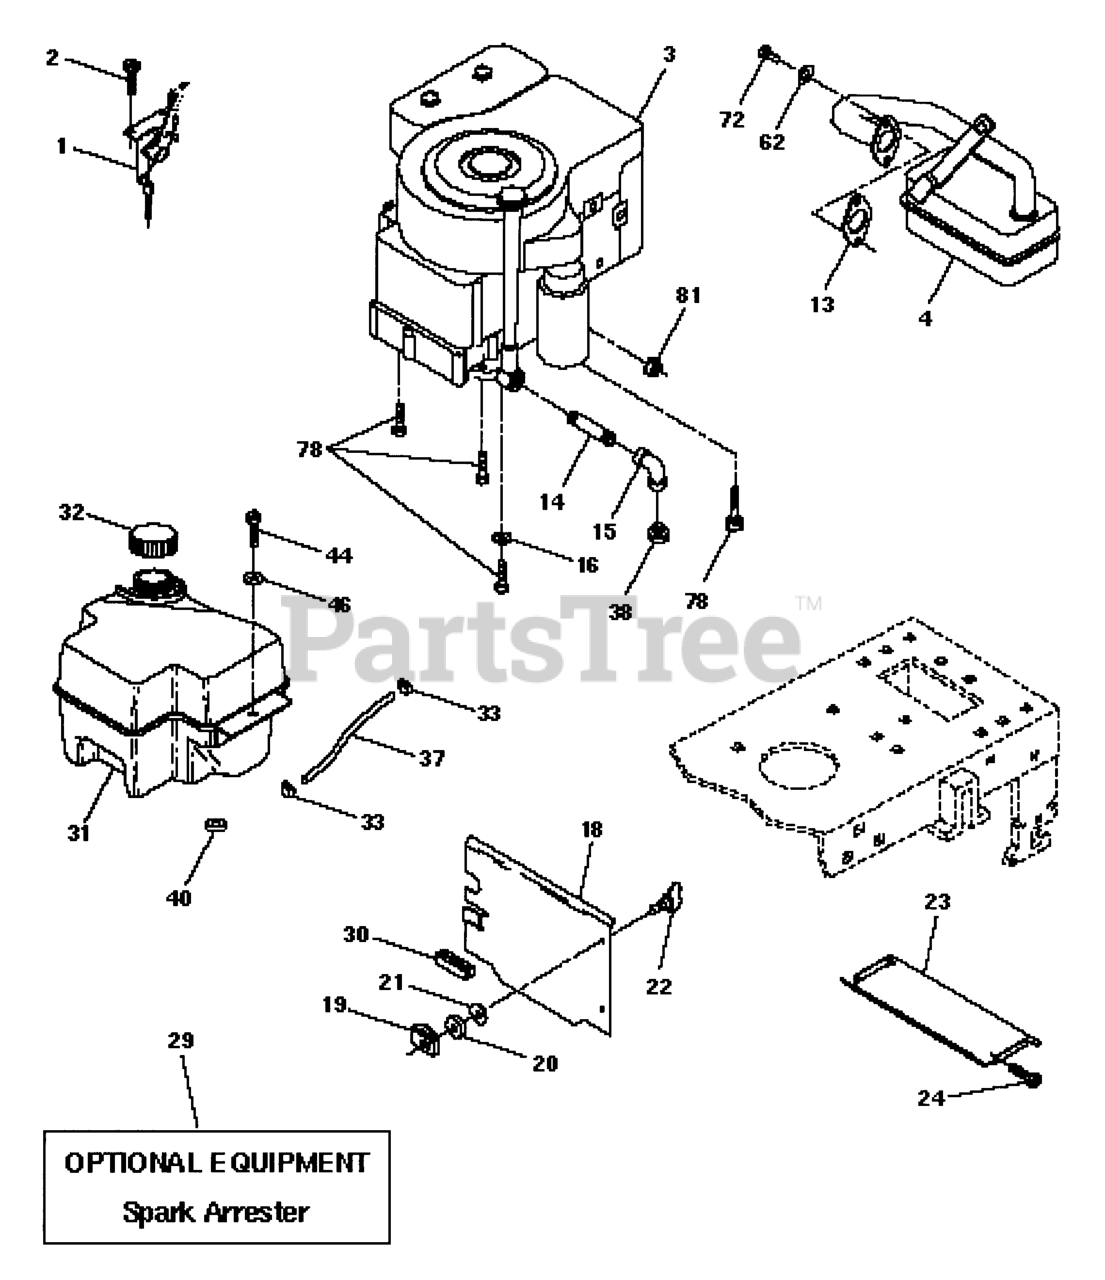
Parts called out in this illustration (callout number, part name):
1	CHOKE CONTROL
2	SCREW LT
4	MUFFLER.SINGLE.B&S.10-12HP
13	GASKET ENGINE
14	Nipple Pipe 3/8 Npt X 3"
15	ELBOW
16	LOCKWASHER
18	HEAT SHIELD
19	RECEPTACLE LT
20	RETAINER LT
21	WASHER
22	STUD 1/4 TURN
23	HEAT SHIELD
29	KIT.SPARK ARRESTOR 794945 B&S
31	FUEL TANK
32	FUEL CAP
33	HOSE CLAMP
37	LINE.FUEL.20
38	Plug Oil Drain
40	BUSHING.SNAP.NYL.BLK.
44	SCREW HEX CRT
46	WASHER
62	WASHER.LOCK.HVY.HLCL.SPR.5/16
72	SCREW
78	SCREW
81	NUT
